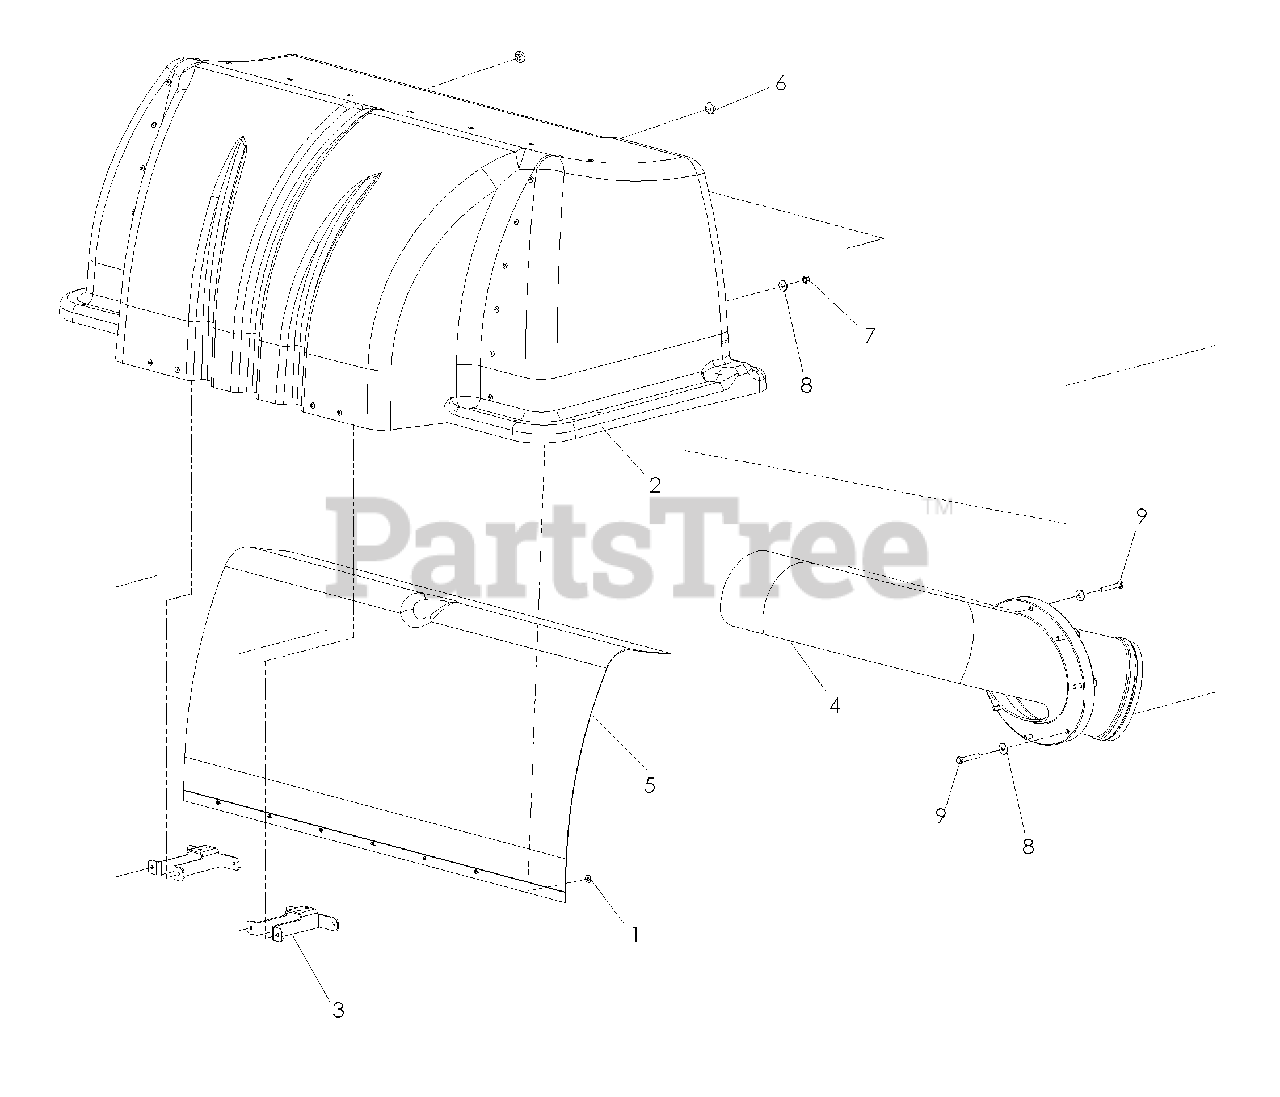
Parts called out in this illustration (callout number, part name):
1	WASHER #10
3	SUPPORT, DRAW LATCH
4	INLET TUBE
5	MESH, POLY DIAMOND
7	NUT 1/4-20 HEX NYLOC
8	WASHER 1/4
9	HCS 1/4-20 x 1 3/4
